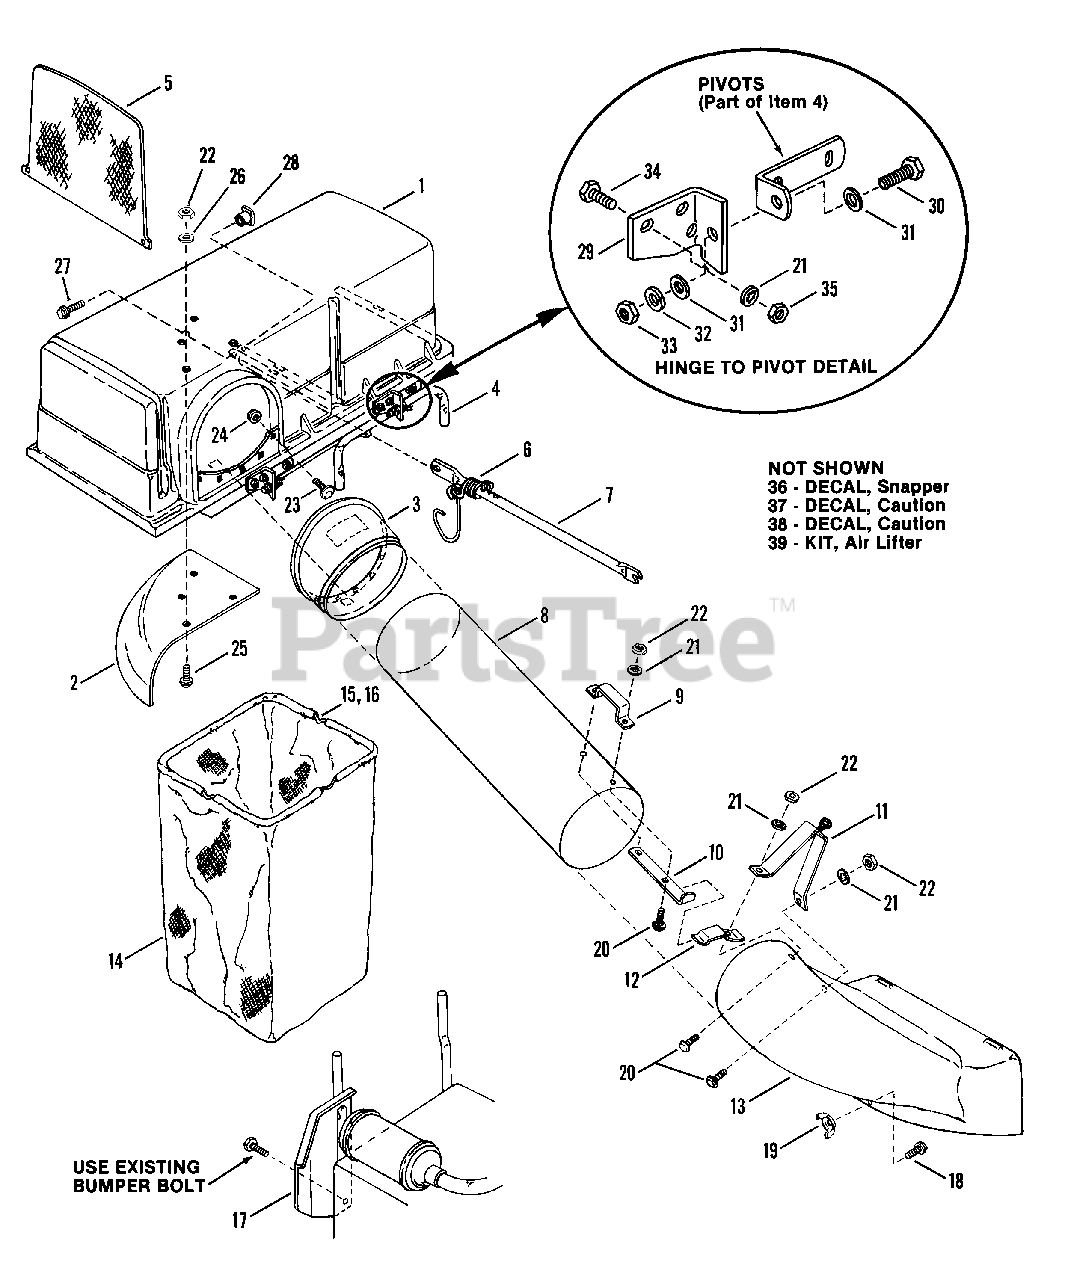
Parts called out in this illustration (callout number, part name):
1	COVER ASSEMBLY
2	SECTOR (Inside Top Baffle)
3	INLET
4	MOUNTING ASSY
5	SCREEN ASSEMBLY
6	SPRING & HOOK ASSEMBLY
7	BRACE
8	TUBE, Grass
9	HANDLE, Tube
10	BASE, Tube Handle
11	BRACKET, Stand-Off
12	LATCH, Tube
13	ADAPTER, (Chute)
14	BAG, Grass Catcher
15	ROD, Bag Support
16	CONNECTOR, Rod
17	SHIELD, Muffler Heat
18	CARRIAGE BOLT, 5/16-18x1 Short Neck
19	WING-NUT, 5/16-18
20	CARRIAGE BOLT, 1/4-20x3/4 Short Neck
21	LOCKWASHER, 1/4 Internal Tooth
22	NUT, 1/4-20 Hex
23	CARRIAGE BOLT, 1/4-20x1/2 Short Neck
24	LOCKNUT, 1/4-20 Flange
25	SCREW, 1/4-20x3/4 Round Hd Machine
26	WASHER, 1/4 SAE (Flat)
27	SCREW, 5/16Cx1-1/2 Flat Head
28	T-NUT, 5/16C
29	HINGE, Top
30	CAPSCREW, 5/16-24x1 Hex Head
31	WASHER, 5/16 SAE (Flat)
32	LOCKWASHER, 5/16 Split
33	LOCKNUT, 5/16-24 Hex
34	CAPSCREW, 1/4-28x3/4 Hex Head
35	NUT, 1/4-28 Hex
36	DECAL, Snapper (11-1/2" Long)
37	DECAL, Caution
38	DECAL, Caution (Grass Bag)
39	KIT, Air Lift
